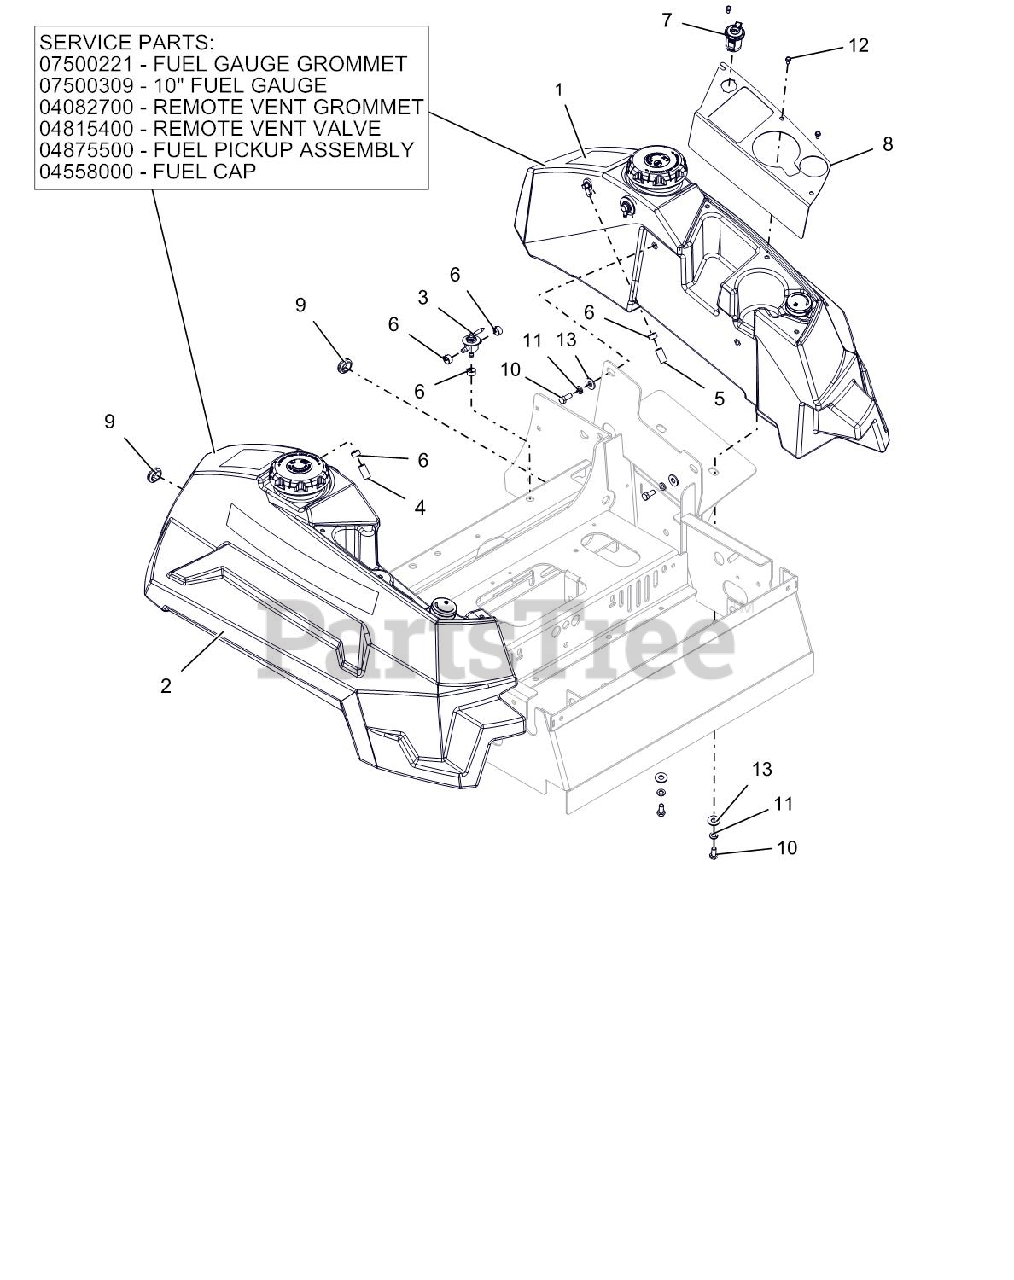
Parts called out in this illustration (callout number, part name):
1	ASM, LH FUEL TANK
2	ASSY-RH, PT400 FUEL TANK
3	VALVE - FUEL
4	HOSE, .25 LOW-PERM BULK GAS
5	HOSE, .25 LOW-PERM BULK GAS
6	CLAMP, FUEL LINE
7	PORT, 12 VOLT POWER
8	CUP HOLDER/POCKET PLATE - RED
9	GROMMET,RUBBER 5/8 ID/1.13 OD
10	@BLT-HEX .31-18X.75 GR5 YWZC
11	@WSHR-LK .31X.078 REG YWZC
12	SCR-MCH 10-24X.38 HWHSTAINLESS
13	@WSHR-FL-STL.38X.875X.083 YWZC
14	GROMMET, FUEL GAUGE
15	GAUGE, REMOTE FUEL SEALED 10"
16	GROMMET, REMOTE VENT NITRILE
17	VALVE, 2-WAY
18	ASSM,LRG TANK FUEL PICKUP LINE
19	CAP, FUEL VENTIN AUTOLOCK
